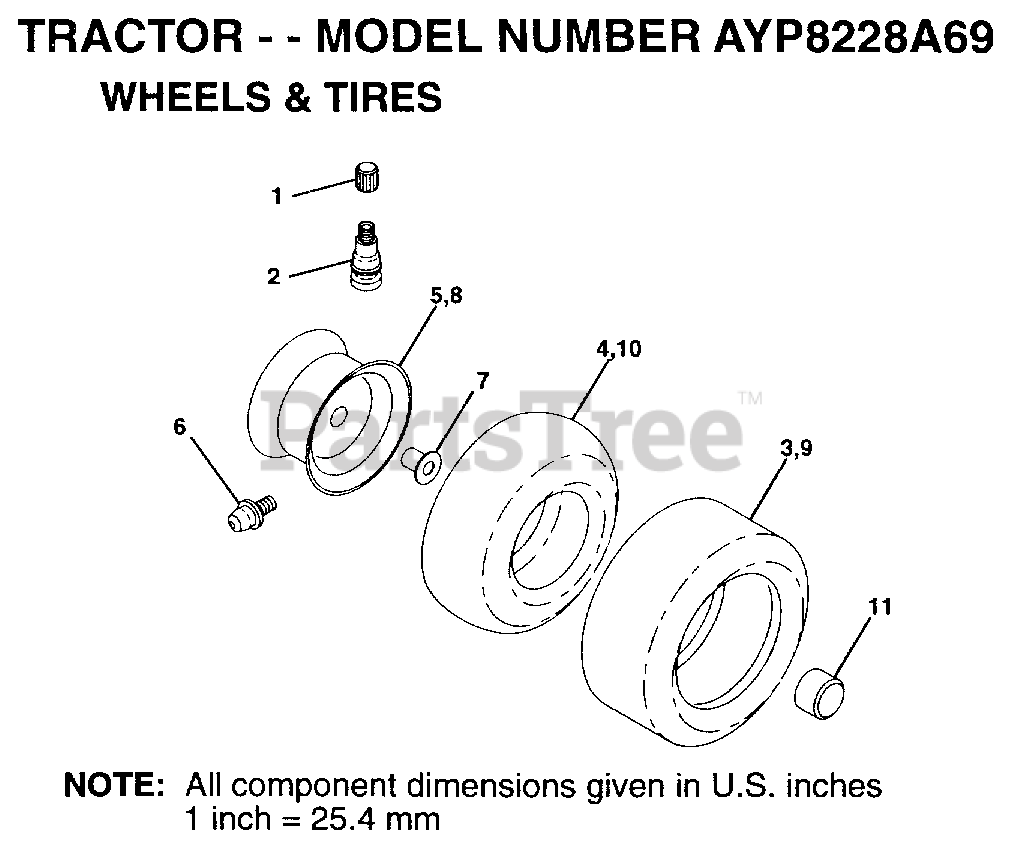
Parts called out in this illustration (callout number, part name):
1	VALVE CAP
2	VALVE STEM LT
4	TUBE.16X6.5/7.5-8
5	"RIM ASM 8"" FRT"
6	ZERK FITTING M
7	"FLANGE, BEARING"
8	"RIM ASM 12"" REAR"
10	TUBE.23X8/10-12
11	HUB CAP
